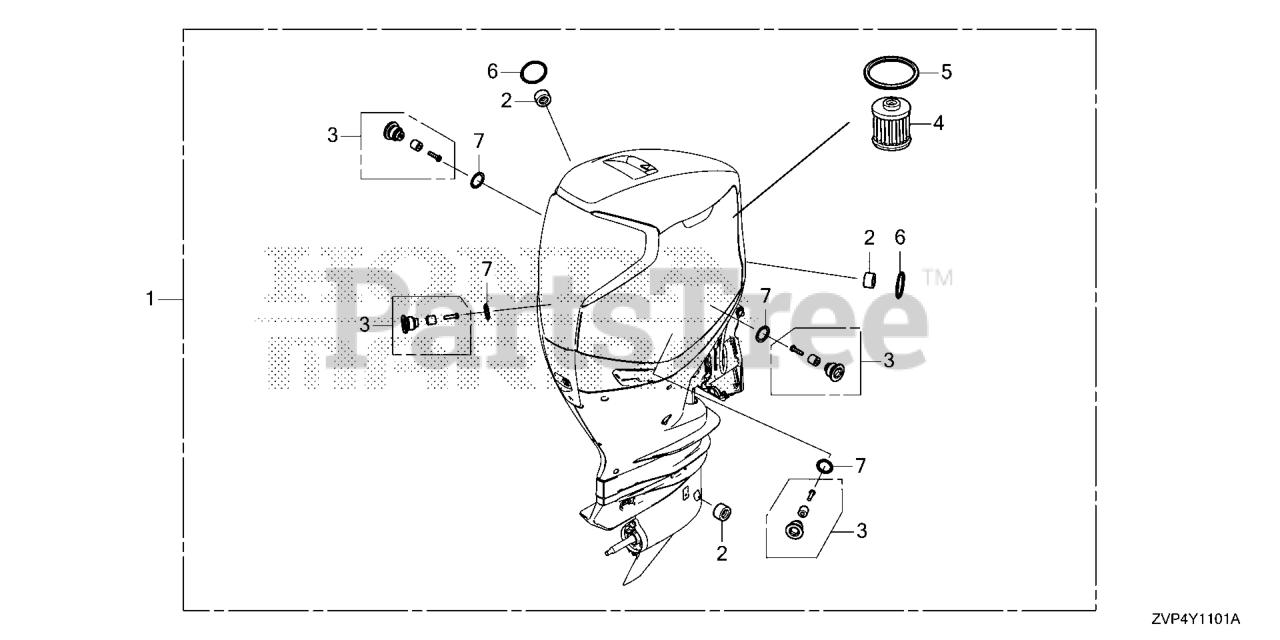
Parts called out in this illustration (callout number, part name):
1	MAINTENANCE KIT (400)
2	METAL, ANODE
3	BOLT, SEALING (22MM)
4	FILTER, FUEL
5	O-RING
6	O-RING (33X2.4)
7	WASHER, SEALING (22MM)
